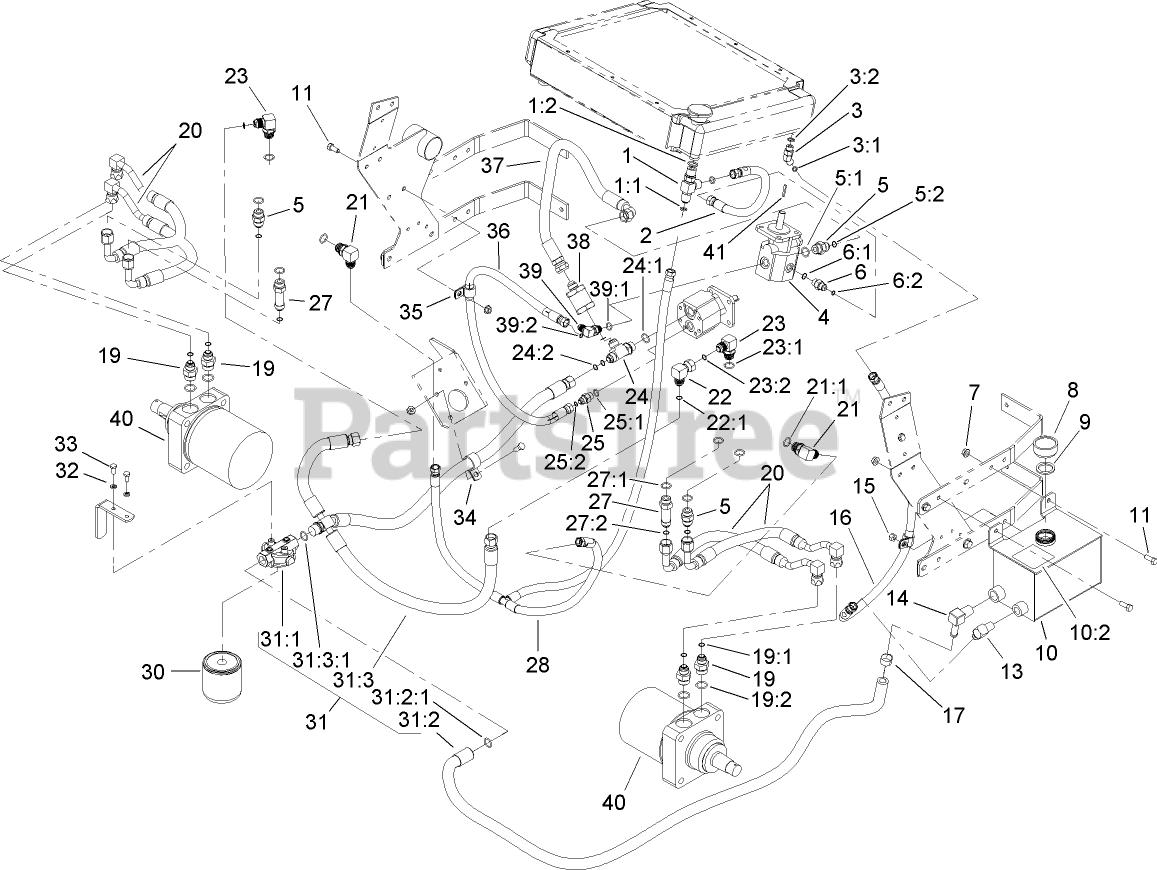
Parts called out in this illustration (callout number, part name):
1	FITTING-HYD, STRAIGHT TEE
1:1	O-RING
1:2	O-RING
2	FAN CASE DRAIN HOSE ASM
3	FITTING-HYD, 45 ELBOW
3:1	O-RING
3:2	O-RING
4	MOTOR-FAN, COOLING
5	FITTING-STRAIGHT
5:1	O-RING
5:2	O-Ring
6	FITTING-STRAIGHT
6:1	O-RING
6:2	O-RING
7	NUT-HF
9	GASKET-CAP, TANK
10	HYD TANK ASM
10:2	DECAL-TANK, HYD
11	SCREW-HH
13	FITTING-ELBOW, 90 DEG
14	FITTING-90 DEG
15	NUT-LOCK, NI
16	TANK RETURN HOSE ASM
17	CLAMP-HOSE
19	Fitting-Straight
19:1	O-RING
19:2	O-Ring
20	HYD HOSE ASM
21	FITTING-ELBOW, 90 DEG
21:1	O-RING
22	FITTING-90 DEG
22:1	O-Ring
23	FITTING-90 DEG
23:1	O-RING
23:2	O-Ring
24	FITTING-TEE
24:1	O-RING
24:2	O-Ring
25	FITTING-STRAIGHT
25:1	O-Ring
25:2	O-RING
27	ADAPTER-HYD, STRAIGHT
27:1	O-RING
27:2	O-Ring
28	CASE DRAIN HOSE ASM
30	FILTER-OIL, HYDRAULIC
31	CHARGE HOSE ASM
31:1	HEAD-FILTER
31:2	FILTER INLET HOSE ASM
31:2:1	O-RING
31:3	PUMP INLET HOSE ASM
31:3:1	O-RING
32	WASHER-LOCK
33	SCREW-HH
34	CLIP-LOOM
35	CLIP-LOOM
36	AUXILLARY PUMP HOSE ASM
37	HOSE-PRESSURE, HIGH
38	FILTER-IN LINE, 50 MICRON
39	FITTING-90 DEG
39:1	O-Ring
39:2	O-RING
40	MOTOR-WHEEL, HYD
41	KEY-SQUARE
